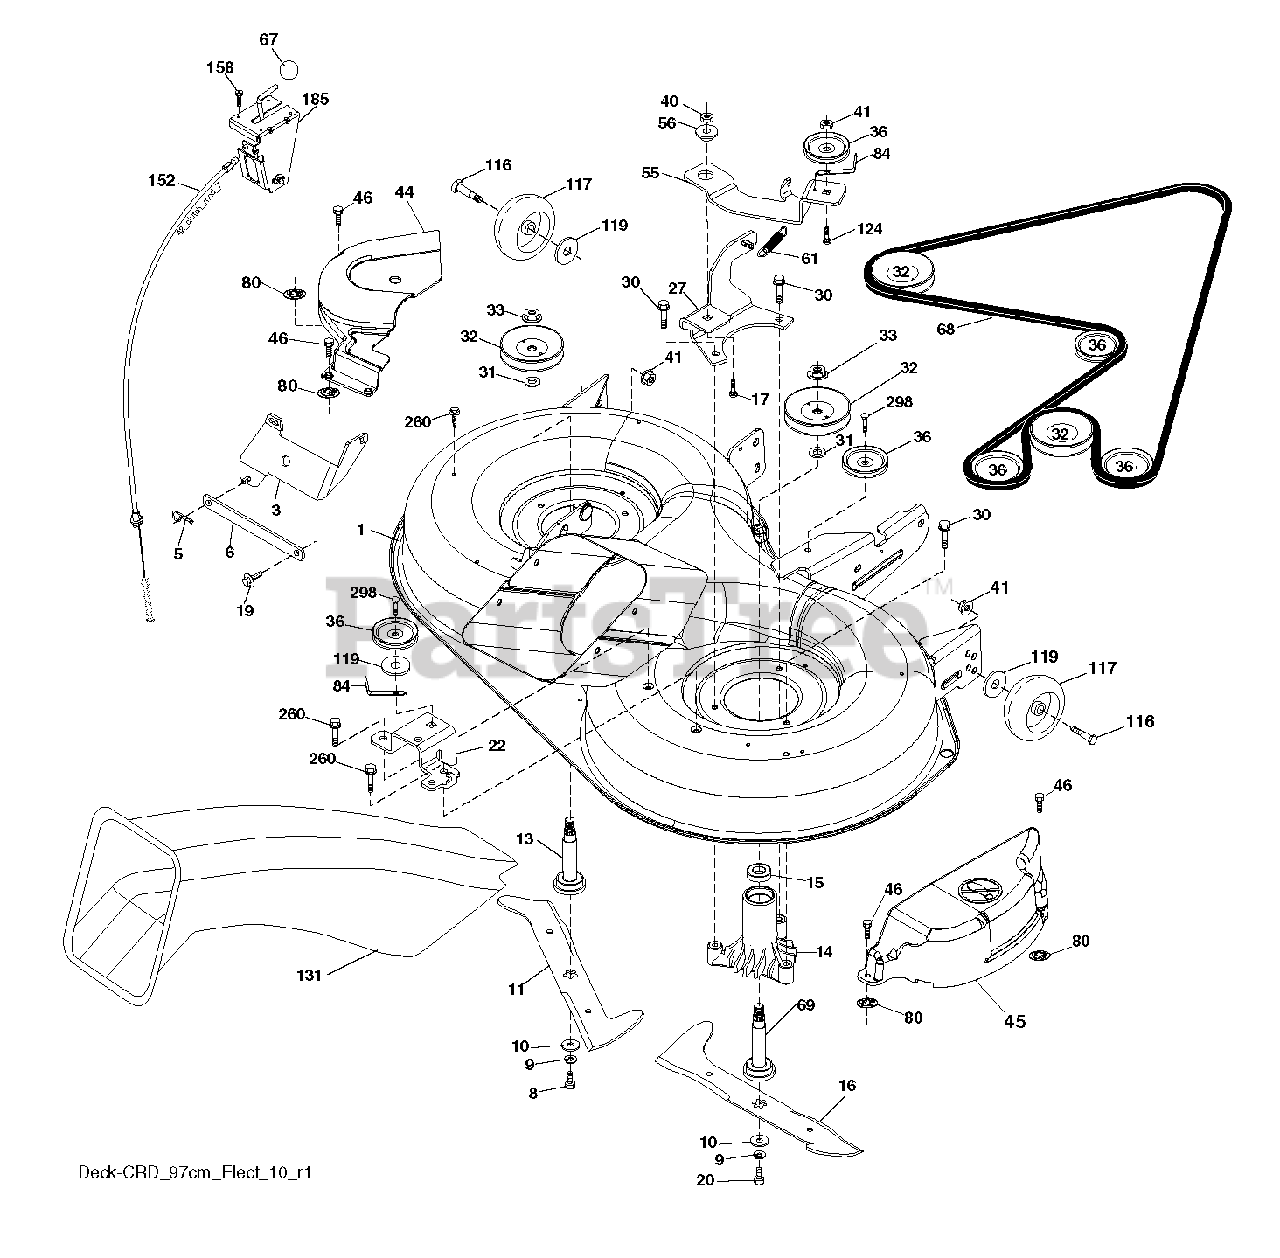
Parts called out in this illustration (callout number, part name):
1	DECK.WLDT.97.CRD.2GWB.
3	BRACKET.ASM.BAR.SWAY.CHASS
5	Retainer Spring
6	BAR.SWAY.92.CRD
8	BOLT.3/8-24X1.25 GR8
9	LOCKWASHER
10	WASHER.BLADE
11	BLADE.3N1.LH.CRD.97
13	SHAFT ASM VENT
14	HOUSING.MANDREL.VENTED (MACHD)
16	BLADE.3N1.RH.CRD.97
17	BOLT.3/8-14X1.25
19	BOLT SHD 5/16-18
20	BOLT.3/8-24X1.25GR8. LHTHRD
22	BRACKET.SUPT.IDLER.REAR.RH
27	BRACKET.ASM.SUSP.REAR.RH.
30	SCREW, WASHER HEAD
31	WASHER.SPACER.MANDREL
32	PULLEY MANDREL
33	NUT.FLANGE.LOCK.TOP
36	PULLEY.IDLER.4.25
41	NUT LOCK FLG 3/8-16 UNC
44	OVER.MANDREL.LH.CRD
45	97.CRD.RH.MANDREL.COVER
46	SCREW.1/4-20X5/8
55	ARM.IDLER.92 CRD.2006
56	SPACER.RETAINER.MOWER
61	SPRING
67	KNOB T (3/8 HOLE)
68	BELT.DRIVE.CRD.97.2010
69	SHAFT.ASM.W/LWR.BRG.RH.THREAD
80	PALNUT 1/4
84	KEEPER, BELT IDLER
116	BOLT.SHOULDER.3/8-16X3-5/8.
117	WHEEL. GUAGE RALLY
119	WASHER
124	BOLT.3/8-16X1.50
131	CHUTE BAGGER
158	SCREW
185	HEAD ASM. CABLE CLUTCH
260	SCREW 3/8-16X1/2
298	SCREW LT
